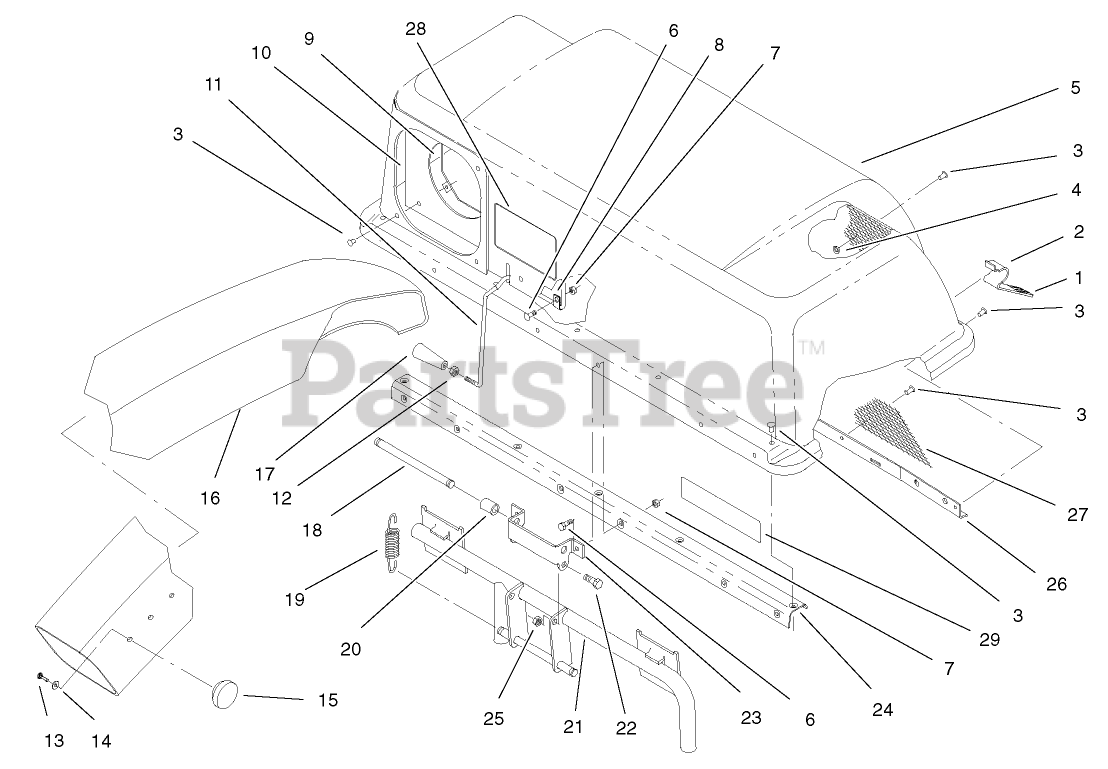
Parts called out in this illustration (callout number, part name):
2	LATCH-BAGGER, TOP
3	RIVET-BLIND
4	WASHER-FLAT
5	TOP-BAGGER
6	SCREW-HH
7	NUT-LOCK, NI
8	CLAMP
9	CLAMP-SEAL
10	SEAL-CHUTE
11	FEELER-FILL, BAG
12	NUT-JAM
13	SCREW-PPHTF
14	WASHER-PLAIN
16	CHUTE-DISCHARGE
17	HANDLE-TAPERED
18	PIN-SPRING
19	SPRING-EXTENSION
20	SPACER
21	FRAME ASM
22	SCREW-HH
23	HINGE-BAG, TOP
24	STIFFENER ASM
25	NUT-LOCK, NI
26	SUPPORT-SCREEN
27	SCREEN-BAGGER
28	DECAL
29	DECAL-CAUTION
